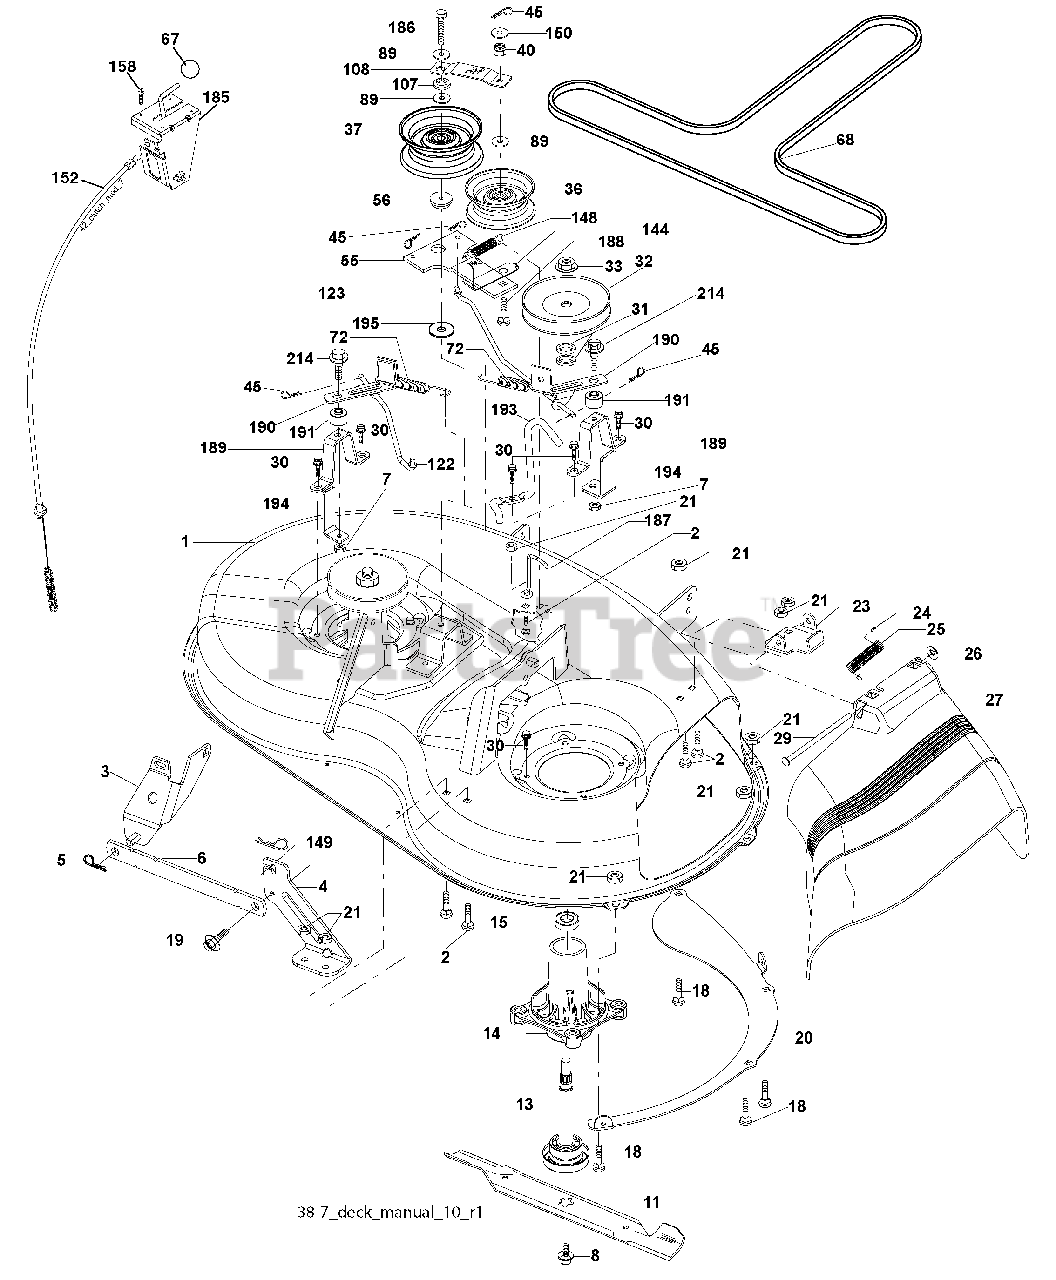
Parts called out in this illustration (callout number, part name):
1	Mower Housing Assembly
2	Bolt Carriage 5/16-18 x 3/4
3	Bracket Asm Fr. Sway Bar
4	Bracket Deck Sway Bar 38"/42"
5	Retainer Spring
6	Bar Sway Deck
7	Nut Lock Hex w/Ins. 5/16-18 unc
8	Bolt 3/8-24 x 1.25 Gr. 8
11	Blade Mower
13	Shaft Assembly, Mandrel, Vented
14	Housing, Mandrel, Vented
15	Bearing, Ball, Mandrel
18	Bolt Rdhd. Sqnk. 5/16-18 x 5/8
19	Bolt, Shoulder
20	Baffle Vortex Front
21	Nut
23	Bracket, Mower Deflector
24	Cap, Sleeve
25	Spring, Torsion, Deflector
26	Nut, Push
27	Shield, Deflector
29	Rod, Hinge
30	Screw Thdrol.
31	Washer, Spacer
32	Pulley, Mandrel
33	Nut, Toplock
36	Pulley, Idler, Flat
37	Pulley Idler Flat
40	Nut, Crownlock 3/8-16 unc
45	Retainer Spring
55	Idler Arm Assembly
56	Spacer, Retainer
67	Knob
68	V-Belt
72	Spring Brake Return
89	Washer 13/32 x 13/16 x 11 Ga.
107	Spacer Retainer
108	Stiffener, Idler Arm
122	Rod, Brake LH
123	Rod, Brake RH
144	Keeper Belt Idler Tension
148	Spring Return Idler
149	Retainer Spring Yellow
150	Washer 9/32 x 3/4 x 10 Ga.
152	Clutch Cable 38"/46"
158	Screw Hex Thd. Cut. 1/4-20 x 1/2
185	Head Asm. Cable Clutch
186	Screw Hex Wsh. Thdrol. 3/8-16 x 2-3/4
187	Keeper Belt
188	Bolt Carriage Idler
189	Stand, Brake
190	Arm, Brake
191	Spacer, Brake
192	Bolt/Washer Asm. 5/16-18
193	Keeper Belt RH Mandrel
194	Guard Brake
195	Washer
214	Bolt/Washer Asm. 5/16-18
214	Brake Assembly
214	Mandrel Assembly
214	Replacement Mower, Complete
